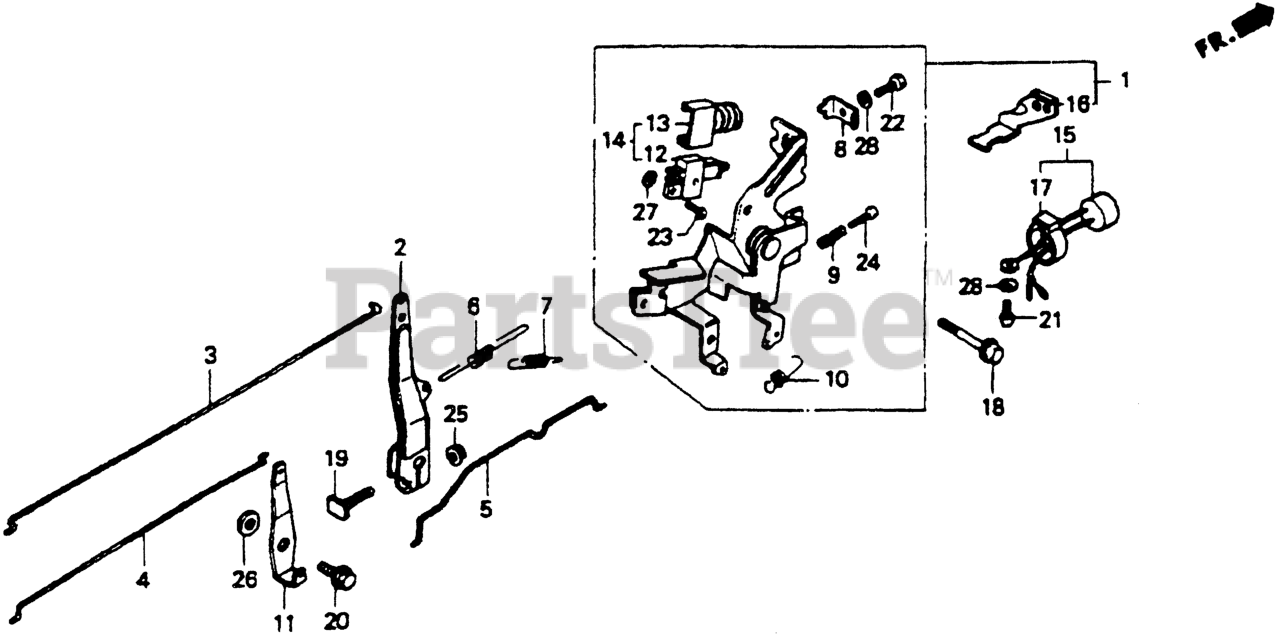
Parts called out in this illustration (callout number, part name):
1	CONTROL ASSY.
2	ARM, GOVERNOR
3	ROD, GOVERNOR
4	ROD, CHOKE
5	ROD, JOINT
6	SPRING, GOVERNOR
7	SPRING, GOVERNOR PRIMARY
8	HOLDER, CABLE
9	SPRING, CONTROL ADJUSTING Use from Engine SN 2327377.
10	SPRING, CABLE RETURN
11	LEVER, CHOKE JOINT
12	SWITCH ASSY., ENGINE
13	COVER, SWITCH
14	SWITCH ASSY., ENGINE STOP
15	BUZZER ASSY.
16	STAY, BUZZER
17	SUSPENSION, AUDIBLE PILOT
18	BOLT, FLANGE (6X12) (CT200)
19	BOLT, GOVERNOR ARM
20	BOLT, FLANGE (6MM)
21	SCREW, TAPPING (5X8)
22	BOLT, RECESSED (5X16)
23	SCREW, PAN (4X14)
24	SCREW, PAN (5X20)
25	NUT, FLANGE (6MM)
26	WASHER, PLAIN (6MM)
27	WASHER, SPRING (4MM)
28	WASHER, SPRING (5MM)
